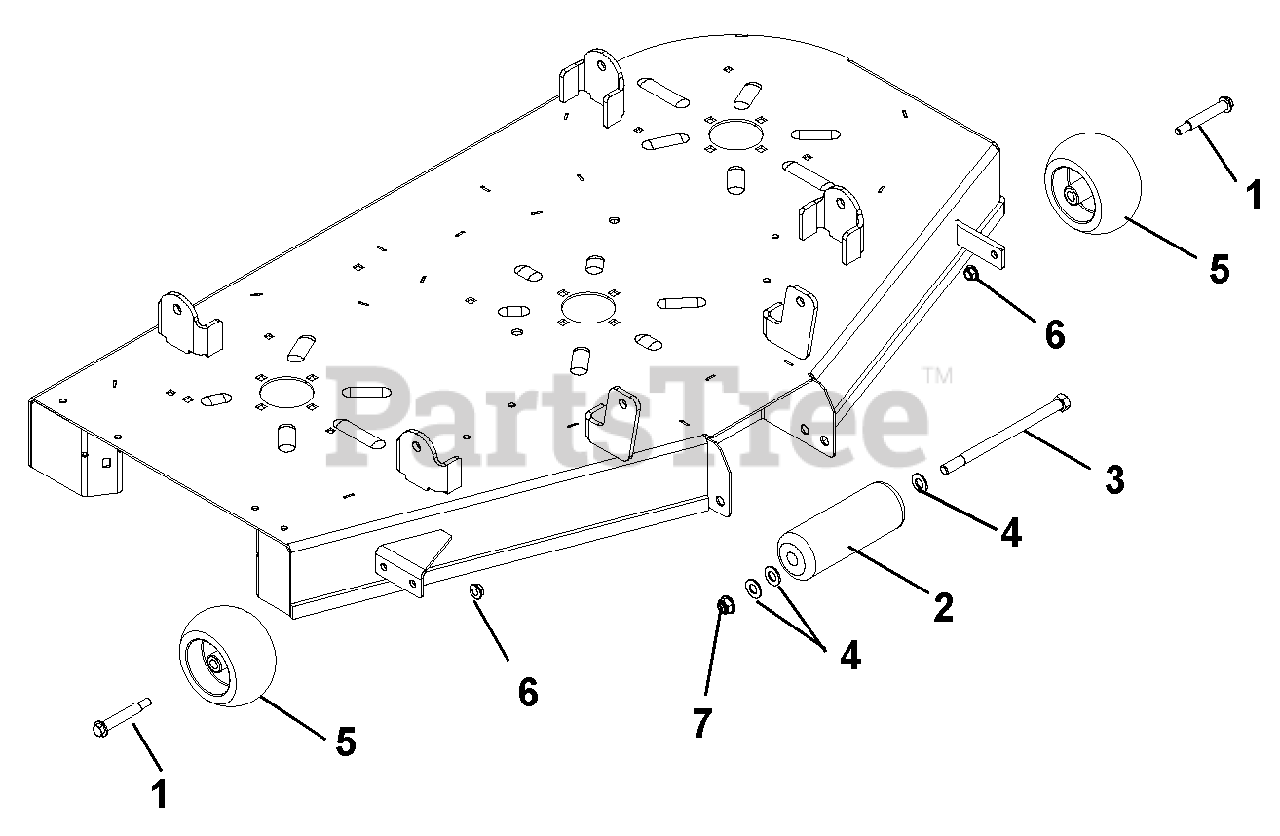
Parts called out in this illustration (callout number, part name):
1	Bolt, Shoulder .38-16 x 2.50 Hex Washer Head Grade 5
3	Bolt, Hex .50-13 x 8.00 Grade 5
4	Washer, Flat Nylon .52 x 1.00 x .08
5	Wheel, Anti-Scalp 5 x 3
6	Nut, Locking Top Flange .38-16
7	Nut, Locking Nylon .50-13
